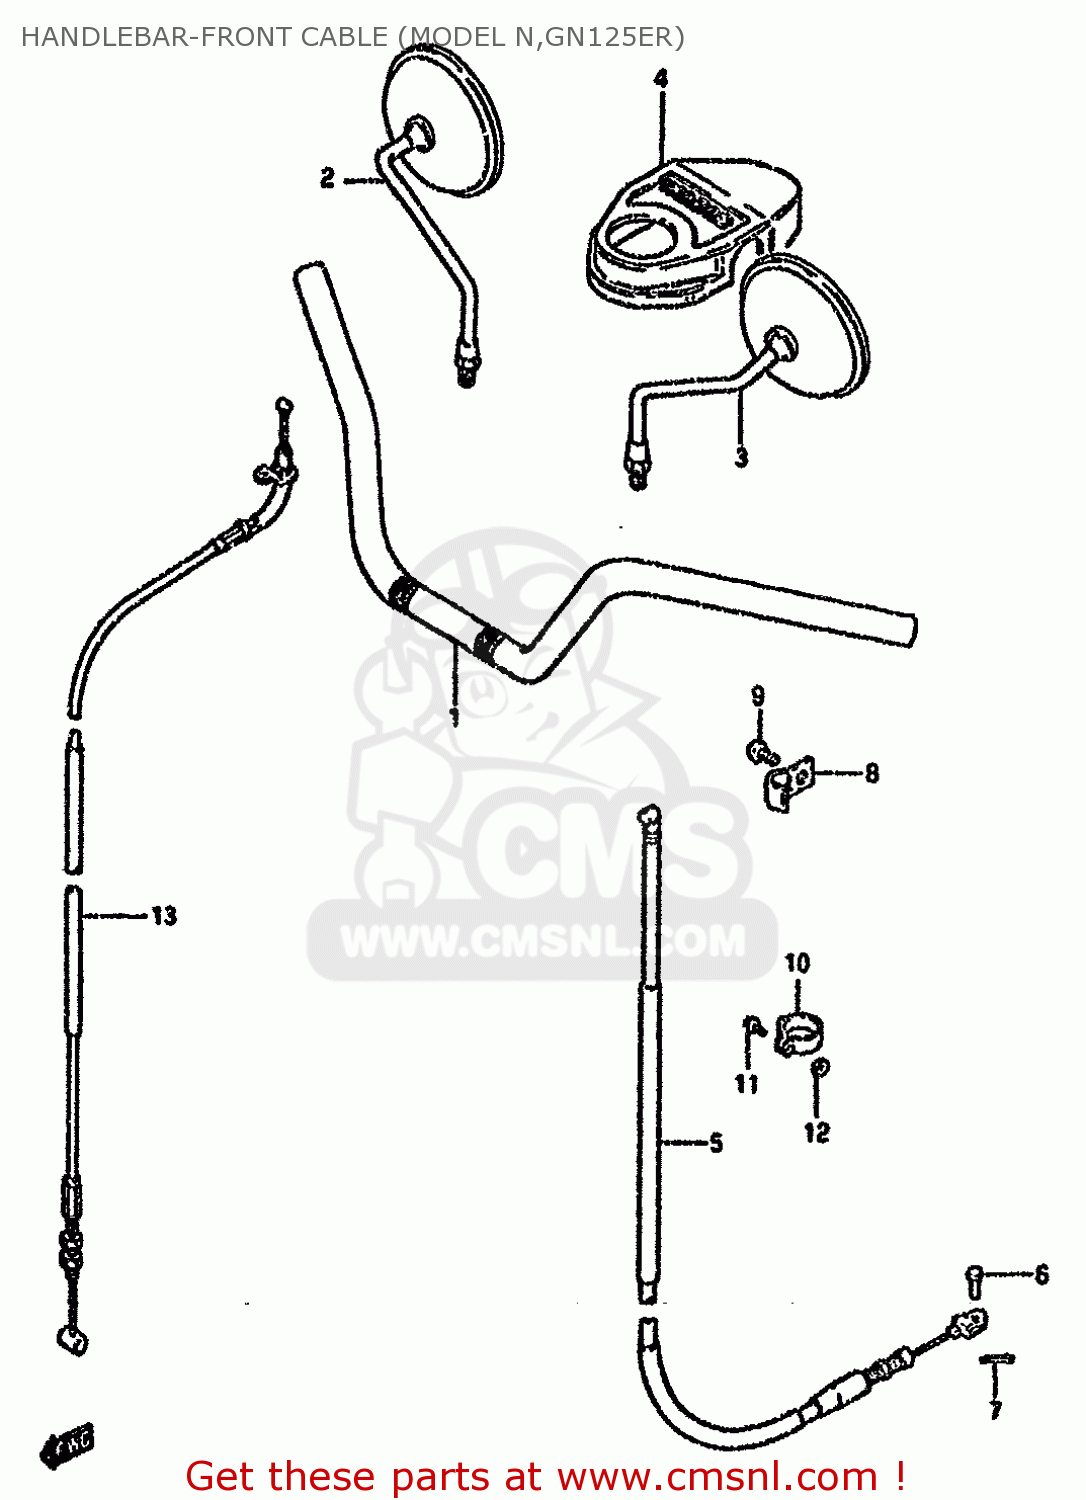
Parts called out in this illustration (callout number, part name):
1	HANDLEBAR
2	MIRROR ASSEMBLY,RIGHT
3	MIRROR ASSEMBLY,LEFT
4	COVER,STEERING HEAD
5	CABLE ASSEMBLY,CLUTCH
6	PIN(L:13)
7	PIN
8	CLAMP,CLUTCH CABLE NO.1
9	SCREW
10	CLAMP,CABLE
11	SCREW
12	NUT
13	CABLE ASSY,THROTTLE
14	PIN(L:13)
15	PIN
16	CLAMP,CLUTCH CABLE NO.1
17	SCREW
18	CLAMP,CABLE
19	SCREW
20	NUT
21	CLAMP
22	CABLE ASSY,THROTTLE
23	CLAMP
